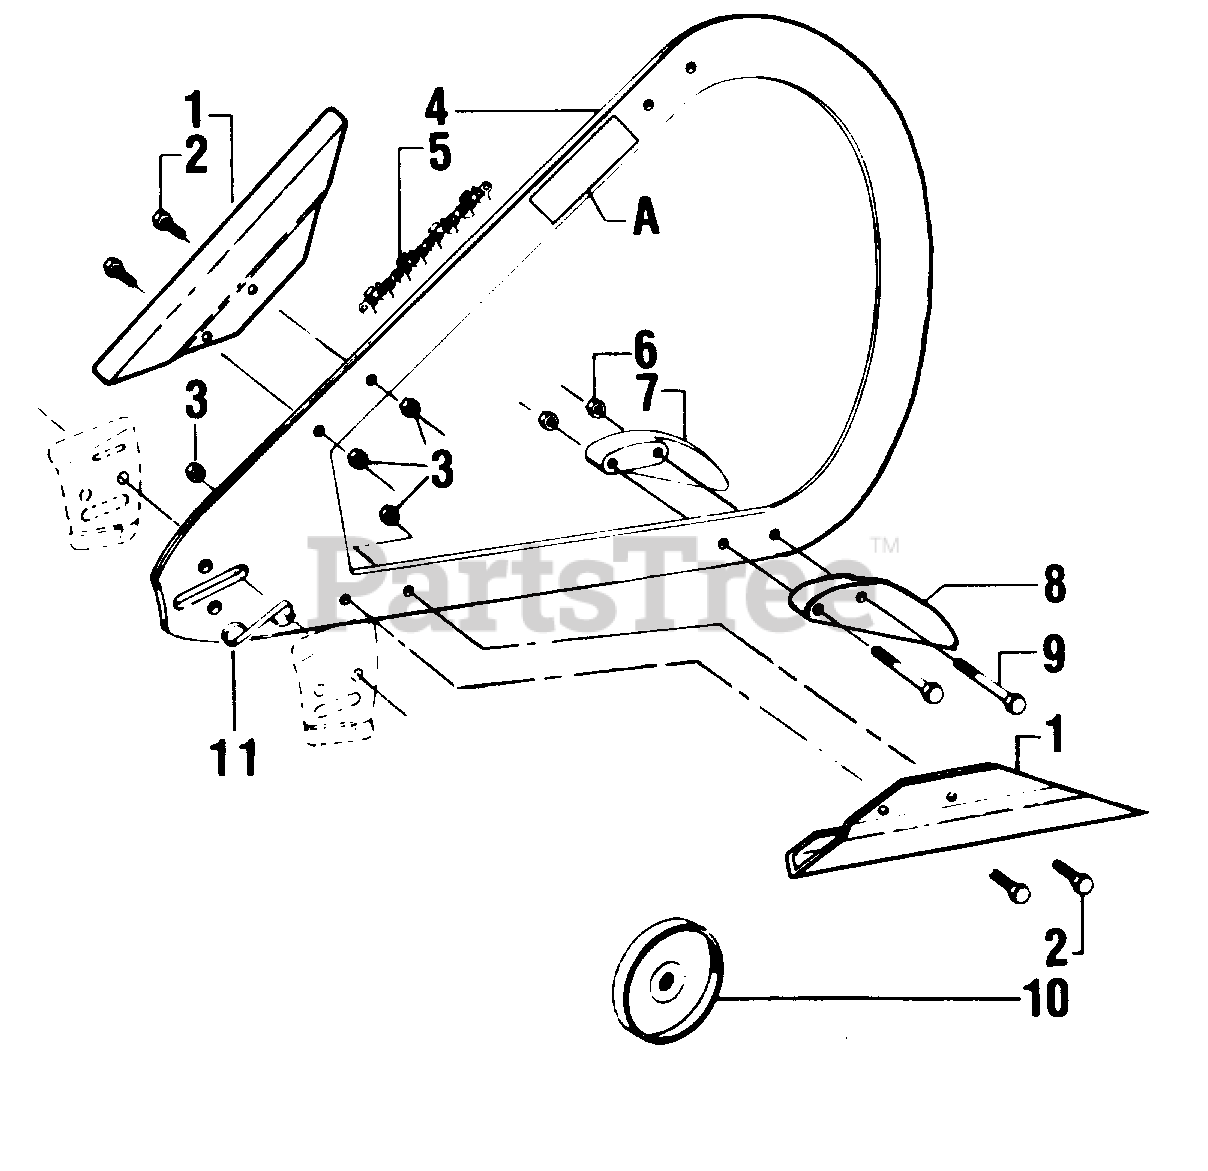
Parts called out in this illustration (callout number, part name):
1	Chain Guard - Upper & Lower
2	Screw - Guard Mtg. (12 - 24 x 5/8 Hex Head)
3	Locknut - 12 - 24
4	Bow Guide (See Bow & Chain Information
5	Chain (See Bow & Chain Information)
6	Locknut - Spike Mtg. (1/4 - 20)
7	Bumper Spike - Left
8	Bumper Spike - Right
9	Screw - Bumper Spike Mtg. (1/4 - 20 x 1- 3/4)Hex Head)
10	Drum and Sprocket Assembly (For .404 pitch only)
11	"S" Clip
A	Decal - Bow Buide Warning
